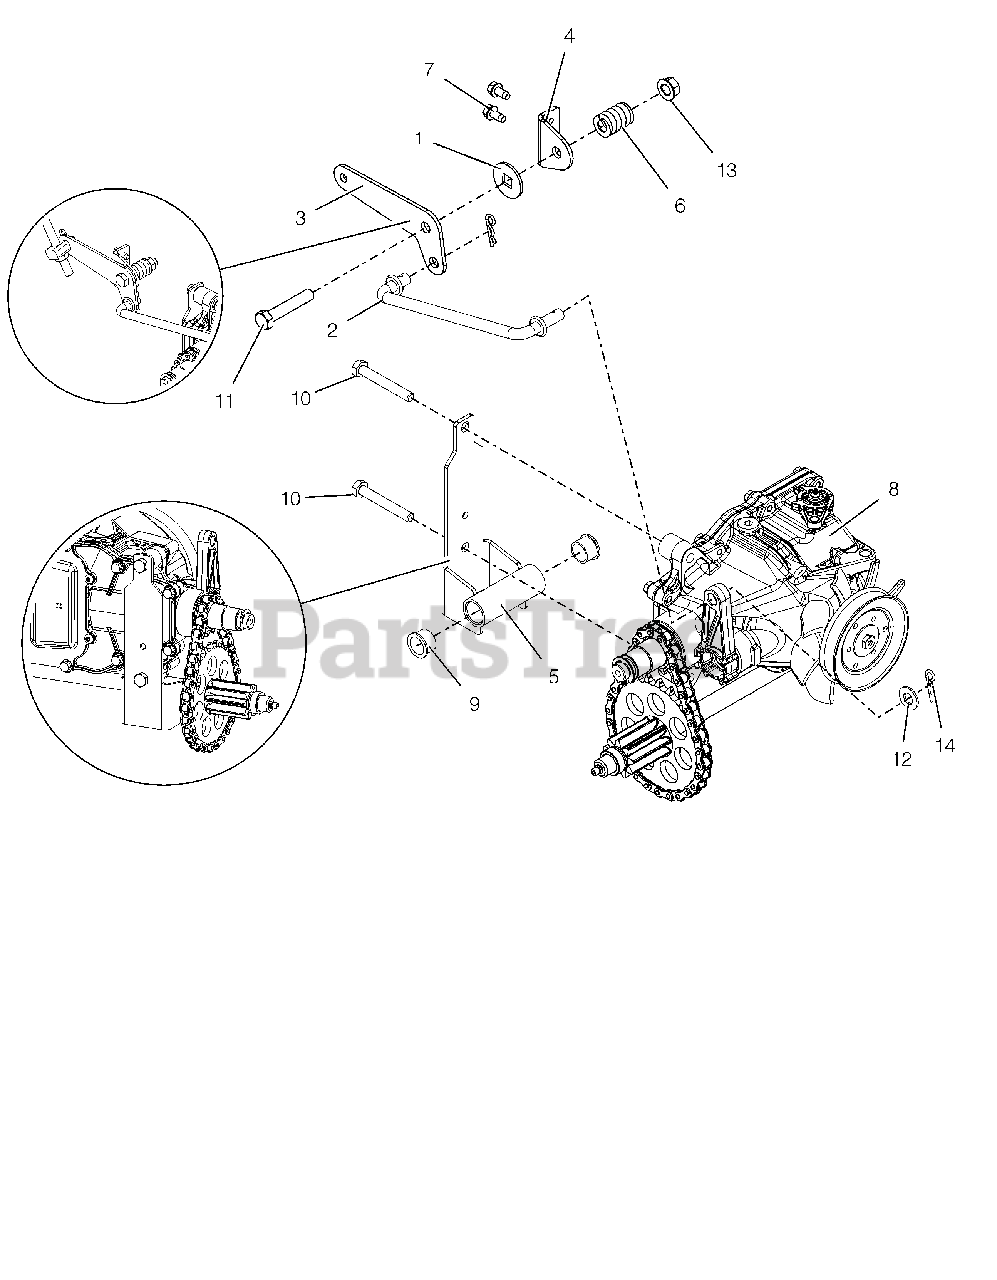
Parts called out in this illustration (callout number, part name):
1	FRICTION WASHER
2	ROD, HYDRO TRANS SHIFT
3	PIVOT, HYDRO TRANS SHIFT
4	BRACKET, HYDRO SHIFT PIVOT
5	TRANS MOUNT, TENSIONING, WHEEL
6	SG-COMP .187X.56X1.62
7	SCR-TAP .25-20X.50 HWH TR YWZ
8	TRANSMISSION, HYDROSTATIC
9	BSHG-FLG .625X.750X.500X.875
10	@BLT-HEX .31-18X2.25 GR5 YWZC
11	@BLT-HEX .38-16X2.00 GR5 YWZC
12	@WSHR-FL-STL.406X.812X.065 YWZ
13	@NUT-LK-TOP-FLG .38-16 YWZC
14	PIN-HAIR INT .08X.18X1.18 YWZC
